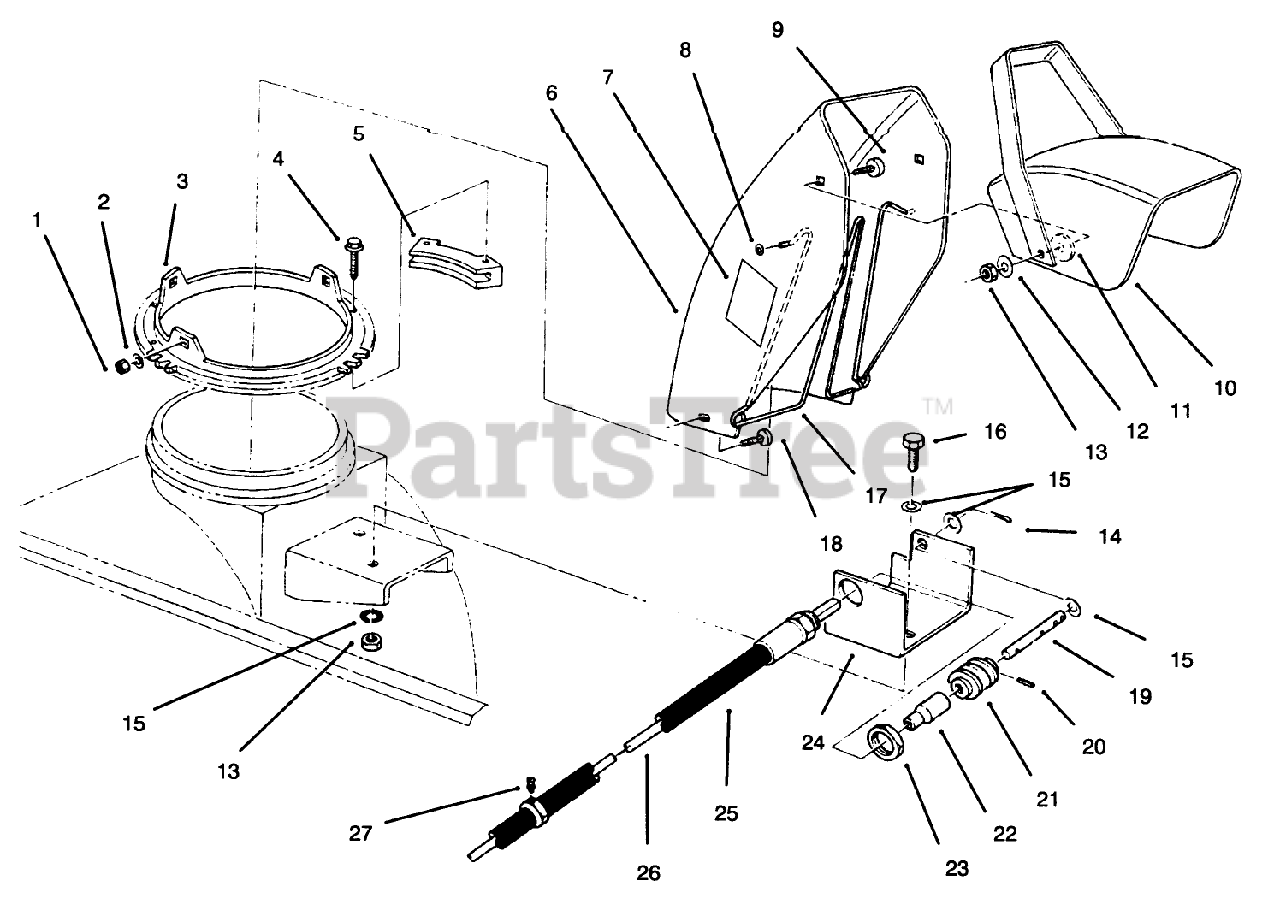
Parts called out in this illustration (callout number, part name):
1	NUT-LOCK, NI
2	WASHER-PLAIN
3	Screw
4	SCREW-SPECIAL
5	RETAINER-CHUTE
6	Chute-Upper (Incl. Ref. #7)
7	NIPPLE
8	NUT-PUSH
9	BOLT-CARR
10	Deflector
11	WASHER-RUBBER
12	WASHER-BELLEVILLE
13	NUT-LOCK, NI
14	PIN-COTTER
15	WASHER-FLAT
16	SCREW-HH
17	CHUTE WIRE
18	SCREW-CARR
19	SHAFT-GEAR, WORM
20	PIN-SPRING
21	GEAR-WORM, CHUTE
22	COUPLER
23	LOCKNUT
24	WORM GEAR BRKT R
25	HOSE ASM
26	FLEX SHAFT
27	FITTING-GREASE
